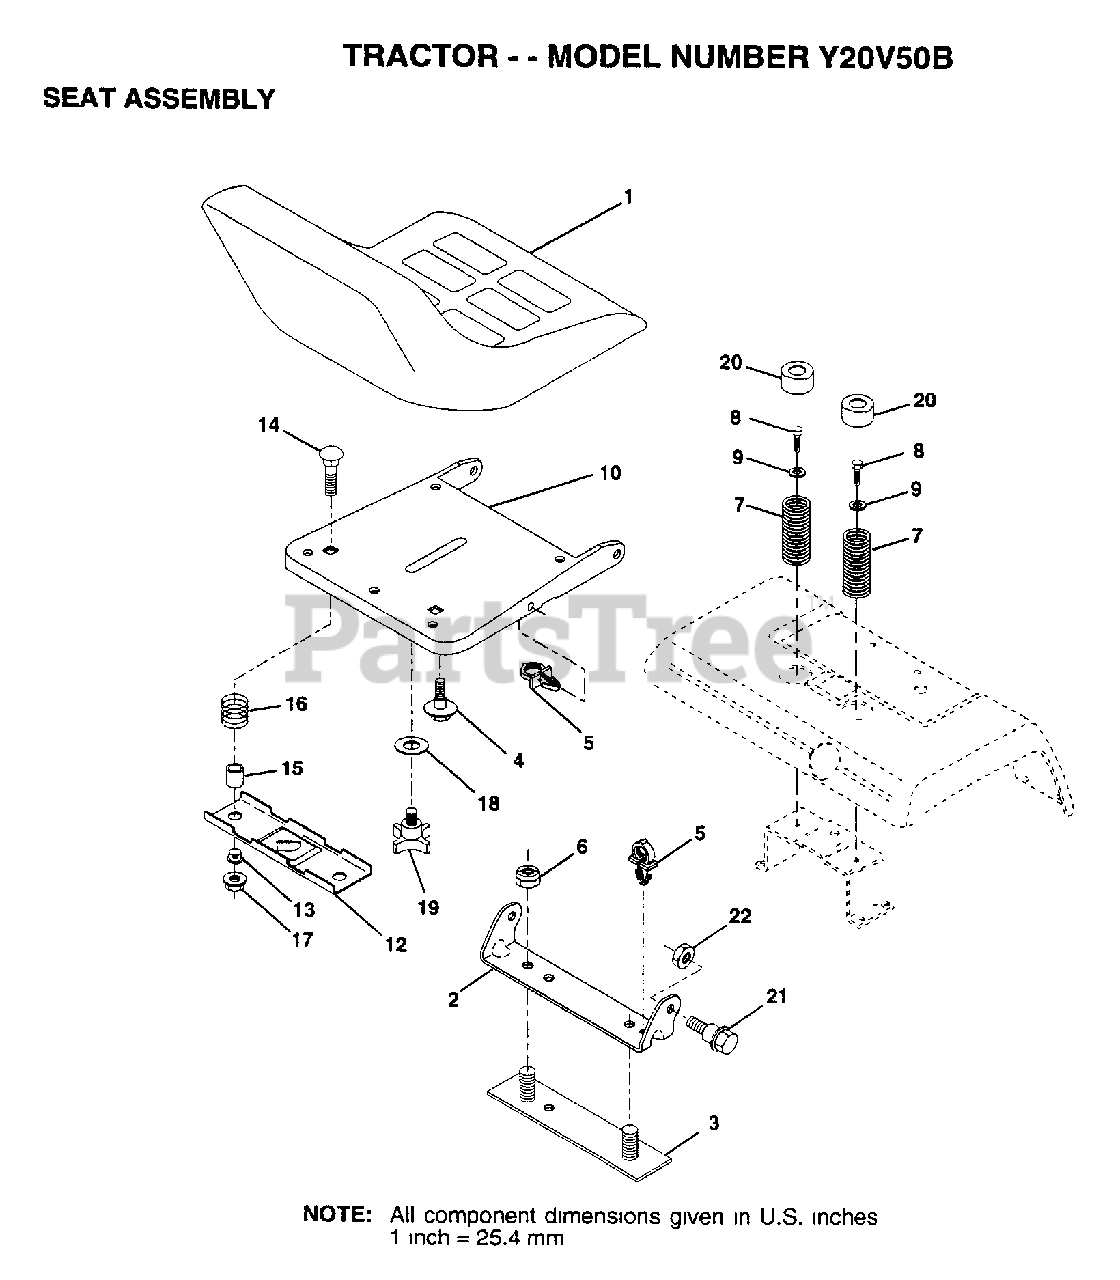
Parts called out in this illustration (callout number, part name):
2	BRACKET PVT SEAT
3	STRAP ASM FENDER
4	"BOLT,SHOULDER"
5	CLIP.PUSH-IN.HING
7	SPRING COMPRESSIO
8	SCREW LT
9	WASHER
12	BRKT SWITCH
13	BUSHING
15	SPACER SPLIT
16	SPRING COMPRESSED
17	SPRING COMPRESSED
18	WASHER
19	"KNOB 1/2"" YT"
20	CAP SPRING
21	BOLT.SHLD.5/16-18
